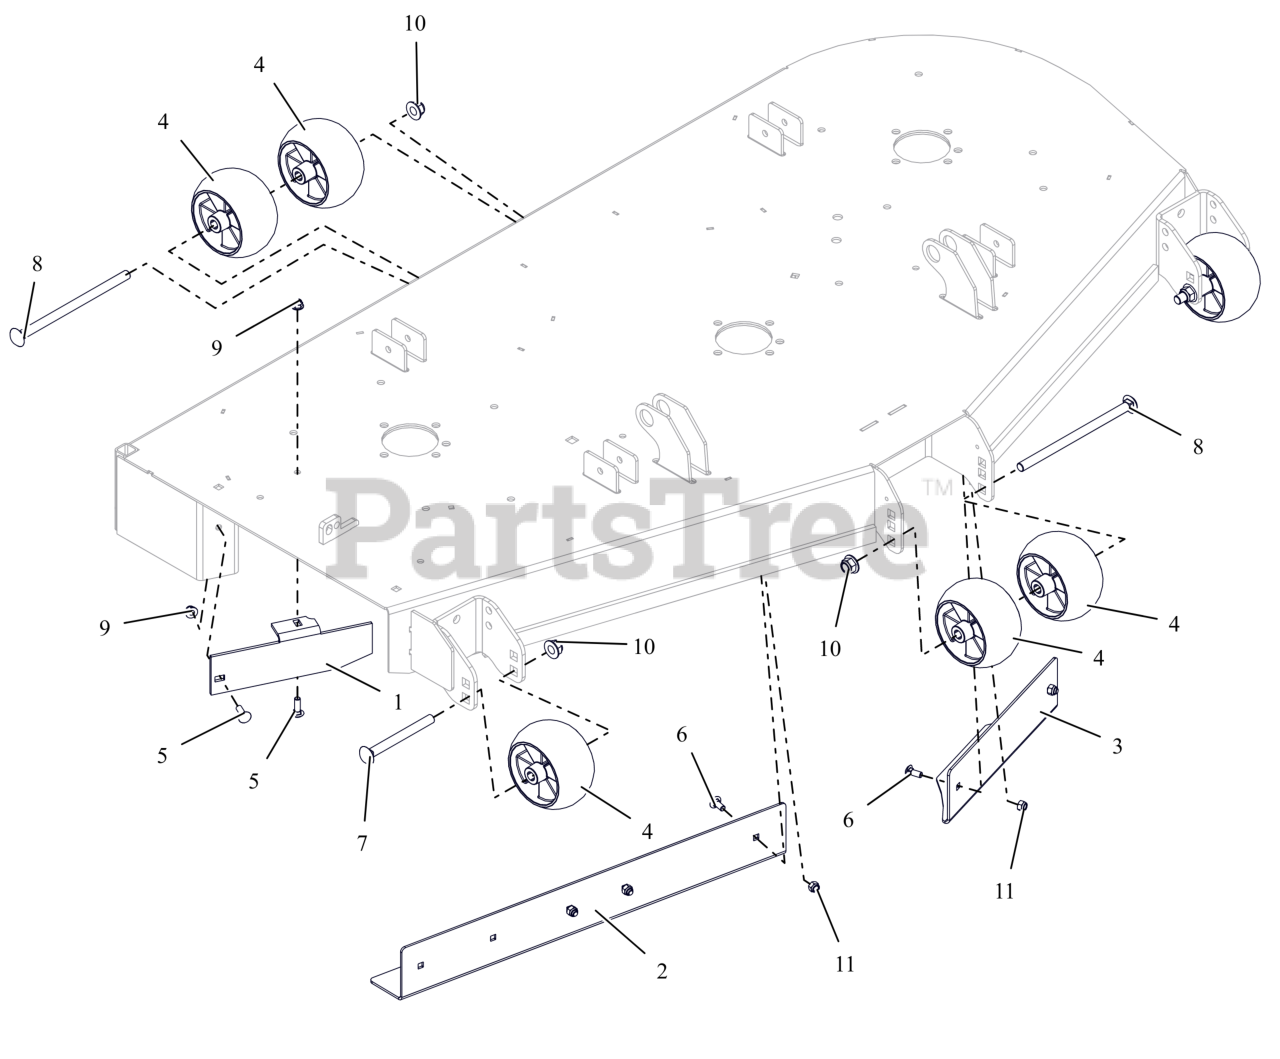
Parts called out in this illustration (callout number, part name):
1	60" DISCHARGE BAFFLE - RED
2	BAFFLE, 60" RH VACUUM (RED)
3	BAFFLE, 60" LH VACUUM (RED)
4	WHEEL, ANTI SCALP - 5X3 CTR W/RIBS
5	BLT,RHSN .31-18X1.00 G5 ZCC
6	BLT,RHSN .31-18X.75 G5 ZCC
7	BLT, RHSN .50-13X5.00 G5 ZCC
8	BTL,RHSN .500-13 X 8.5S G5 ZCC
9	NUT,NYL-FLG .31-18 GF ZCC
10	NUT,NYL-FLG .50-13 GF ZCC
11	NUT,NYL .31-18 G5 ZCC
